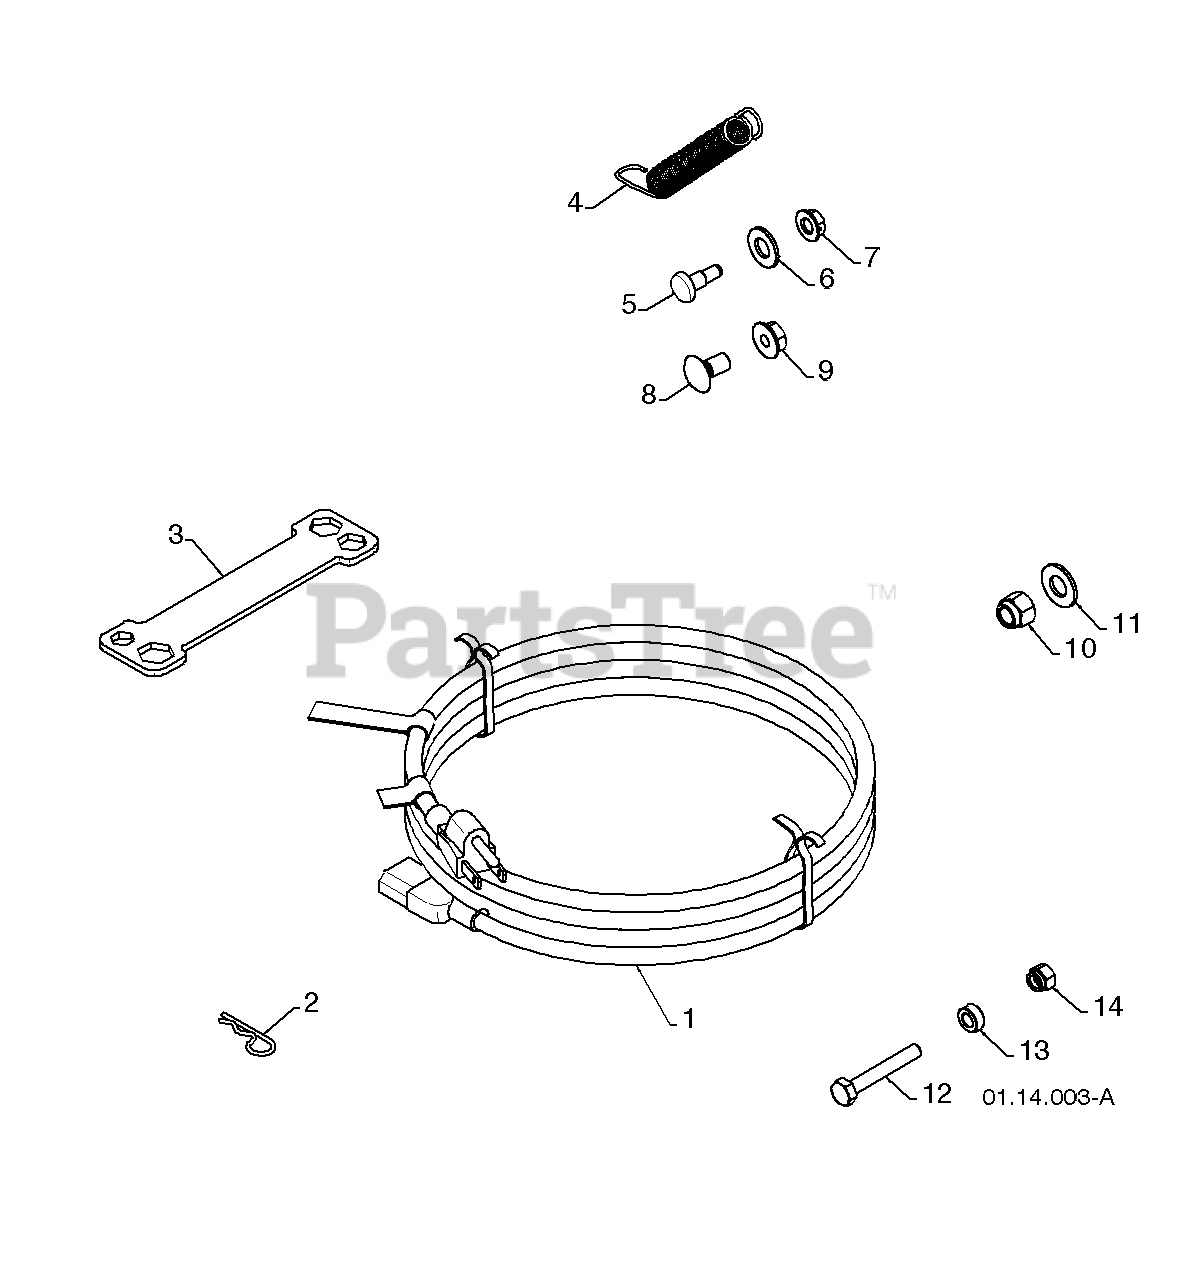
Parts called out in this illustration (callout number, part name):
1	POWER CORD
2	RETAINER PIN
3	WRENCH
4	REMOTE SPRING
5	SHOULDER BOLT 1/4-20
6	NYLON WASHER 1/4-20
7	LOCKNUT 1/4-20
8	CARRIAGE BOLT 5/16-18 X 5/8
9	LOCKNUT 5/16-18
10	LOCKNUT 3/8-16
11	WASHER 3/8
12	SHEAR BOLT 1/4-20 X 1-3/4
14	LOCKNUT 1/4-20
